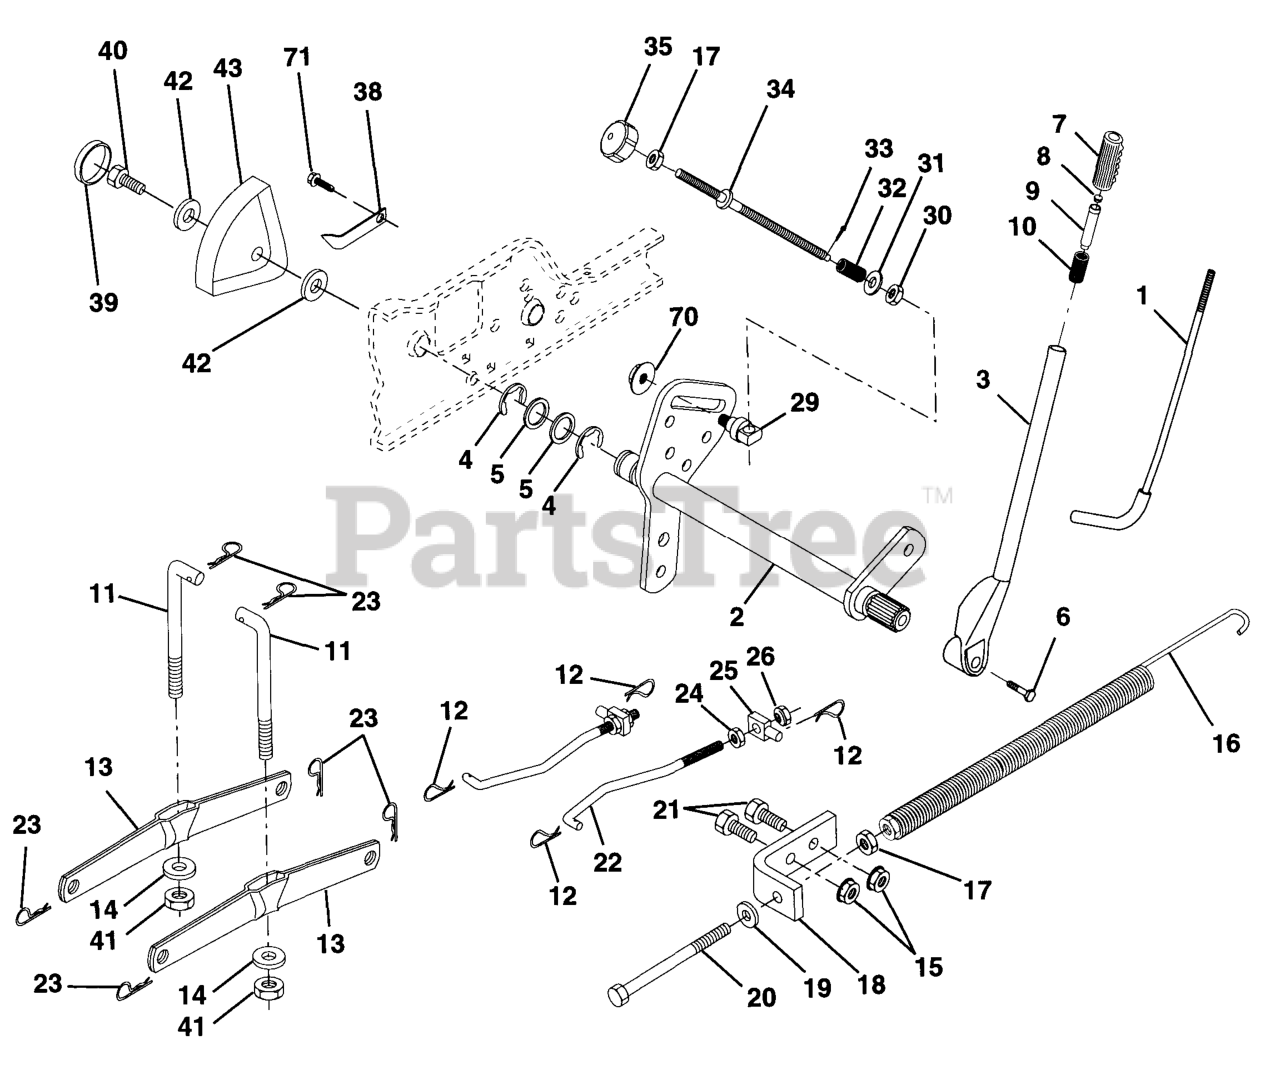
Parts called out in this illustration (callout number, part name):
1	LEVER ROD LT
2	SHAFT ASM., LIFT VGT
3	LIFT LEVER KIT
5	Washer 29/32 x 1-1/4 x 16 Ga.
6	BOLT
7	GRIP HANDLE
8	PLUNGER BUT KIT
9	PLUNGER BUT KIT
10	SPRING**
11	LINK LIFT
12	SPRING RETAINER
13	ARM.REAR.SUSPENSION
14	BEARING PIVOT
16	LIFT SPRING
17	NUT
19	WASHER
21	BOLT
22	FRONT LINK
23	RETAINER-SPRNG RB
24	NUT.HEX.JAM.1/2-13
25	TRUNION
26	NUT.LK.W/WSH.1/2.
32	SPRING.COMP.INF.H
33	COTTER PIN
34	ROD.LIFT.ADJUSTABLE
35	KNOB INF 3/8-16
36	SCREW
38	POINTER HGT
40	SCREW.THDROL.5/16-18X3/4.TTY
41	NUT CROWNLOCK 3/8-24
43	HEIGHT INDICATOR
70	NUT
